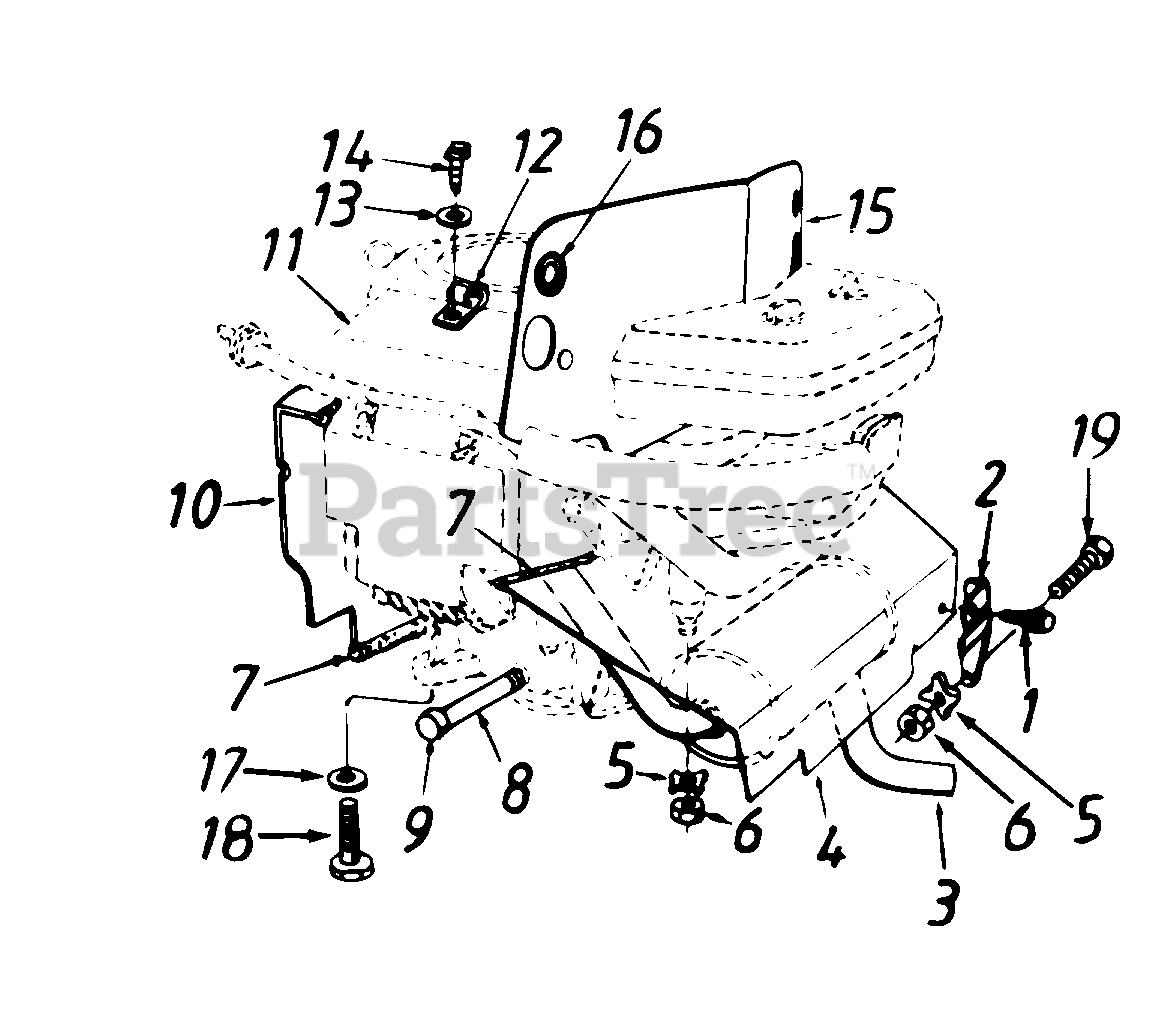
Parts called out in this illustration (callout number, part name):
1	Hex AB-Tap Scr. 1/4 x .62"
3	Muffler
4	Front Heat Shield
5	Spec. L.-Wash. 5/16 x .88"
6	Hex Nut 5/16-18 Thd.
7	Trim Strip 12" Lg.
8	Pipe Nipple
9	Oil Drain Cap
10	Rear Baffle
11	Engine
12	Clamp
13	Fl-Wash. .188" I.D. x .438"
14	Truss Mach. AB-Tap Scr. #10 x .5" Lg.
15	Heat Shield
16	Rubber Grommet
17	Fl-Wash. .406" I.D. x 1-1/4" O.D.
18	Hex L-Wash. TT-Tap Scr. 3/8-16 x 1.5" Lg.
19	Hex Bolt 5/16-18 x 5/8" Lg.
